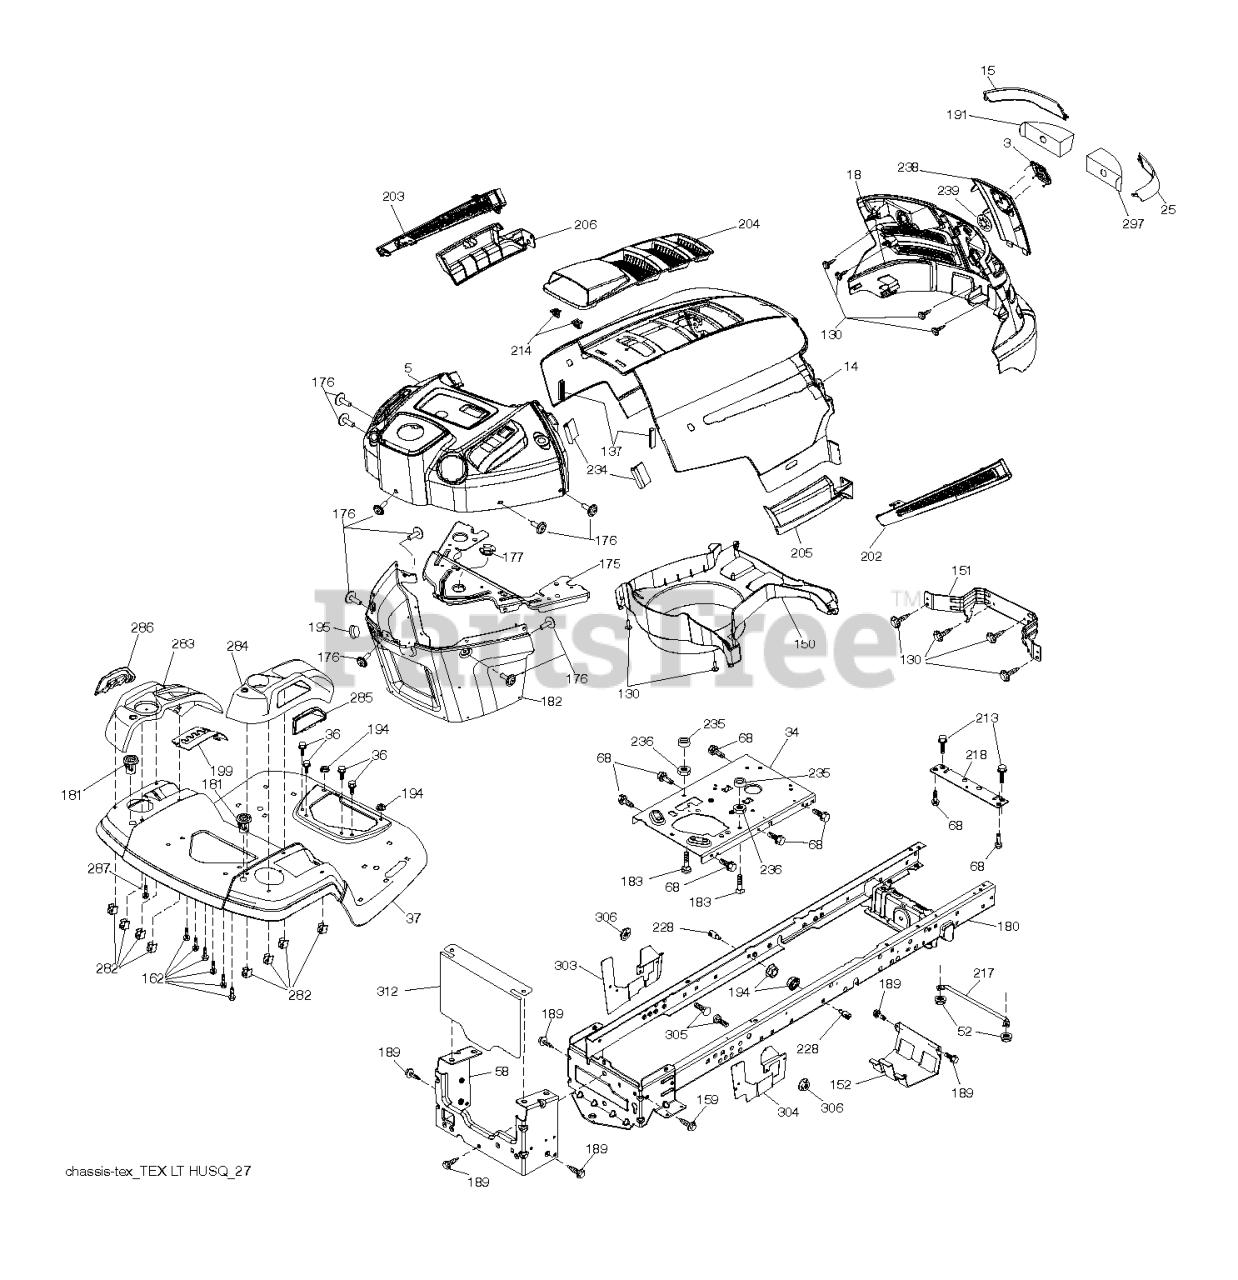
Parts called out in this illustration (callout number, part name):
3	RP LOGO
5	DASH
14	HOOD
15	LENS.HUSQVARNA LT.LH
18	RP GRILLE/LENS ASM.
25	LENS.HUSQVARNA LT.RH
34	PLATE.ENGINE.WELDED.CHASSIS
36	SCREW 5/16"
37	RP FENDER.TLT.FS.W/CPH.422
52	LOCKNUT
58	DRAWBAR UPPER 2PC SMALL FENDER
68	Screw 5/16-18 x 1/2 Hex, Self Tapping 5/16-18 x 1/2
130	SCREW.#10 X 0.750.BOS
137	BUMPER DASH
151	BRACKET PIVOT
152	SHIELD.BROWNING.W/TEX
159	SCREW, 3/8-16X3/4
162	SCREW.HI-LO.CONSOLE
175	CROSSMEMBER
176	SCREW.#10-24X5/8.RN.QU
177	BUSHING STEERING
180	CHASS.WLDMNT.TL.12GA/2P.48/54
181	BUSHING.MNT.FEND.CRGO.
182	DASH.LOWER.PREDATOR LT
183	BOLT.5/16-18X1-1/4 FULL.THREAD
189	SCREW
191	INSERT REFLECTIVE
194	NUT LOCK HEX FLANGE 5/16-18
195	PLUG DASH
199	PLATE.DECK.LIFT.HUSQ.LT
202	VENT SIDE HOOD RH
203	VENT SIDE HOOD LH
204	VENT TOP HOOD
205	SKIRT SIDE RH
206	SKIRT SIDE LH
213	BOLT
214	CLIP.RETAINER.TINNER.
217	ROD.PIVOT.HOOD
218	X-PIECE.HOOD.STOP.NON/
228	STUD.FASTNER.W/ANTI-ROTATE
234	BUMPER.HOOD.TEX.HUSQVARNA
235	SPACER FENDER
236	NUT.CENTERLOCK.5/16-
238	TRIM
282	CLIP.RETAINER.CONSOLE.LT.HUSQ
283	CONSOLE.DECK.LIFT.HUSQ.N/FR.GR
284	CONSOLE.SHFT.HYD,HUSQL
285	CONSOLE INSERT RH
286	CONSOLE.INSRT.LH.HUSQ.LT.BLACK
287	SCREW 1/4X20
297	INSERT.REFLECTIVE.RH.
303	SHIELD CHASSIS LEFT
304	SHIELD CHASSIS RIGHT
306	NUT LOCK FLG 3/8-16 UNC
